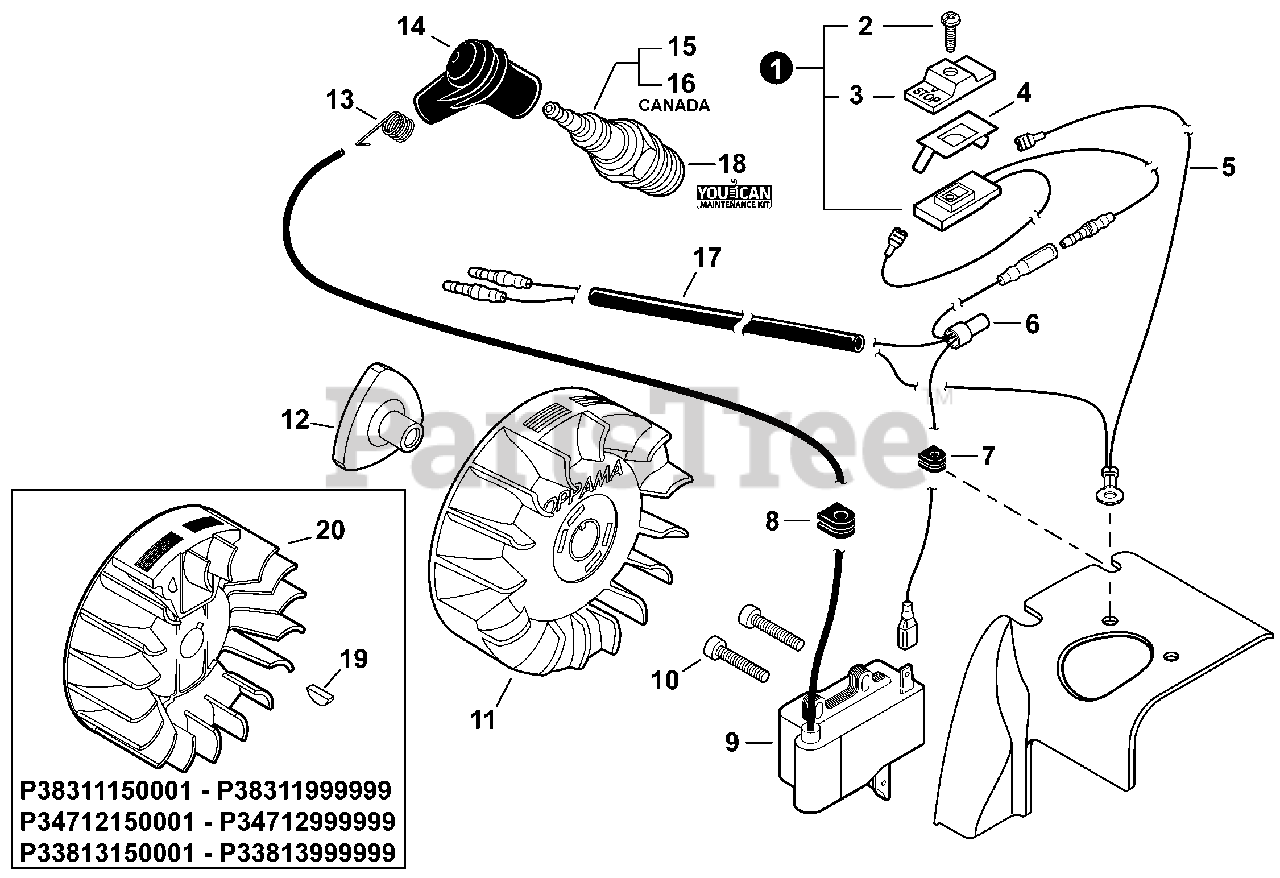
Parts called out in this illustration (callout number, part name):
1	SWITCH ASSY, ON-OFF
2	SCREW 3×10
3	KNOB, SWITCH
4	TERMINAL, LEAD
9	COIL, IGNITION
10	BOLT, TORX 4×20
11	FLYWHEEL
12	HUB, FAN
13	TERMINAL, SPARK PLUG
14	CAP, SPARK PLUG
15	SPARK PLUG - BPM8Y
16	SPARK PLUG - BPMR8Y
17	TUBE, INSULATOR
18	TUNE-UP KIT - YOUCANT
19	KEY, WOODRUFF
20	FLYWHEEL
